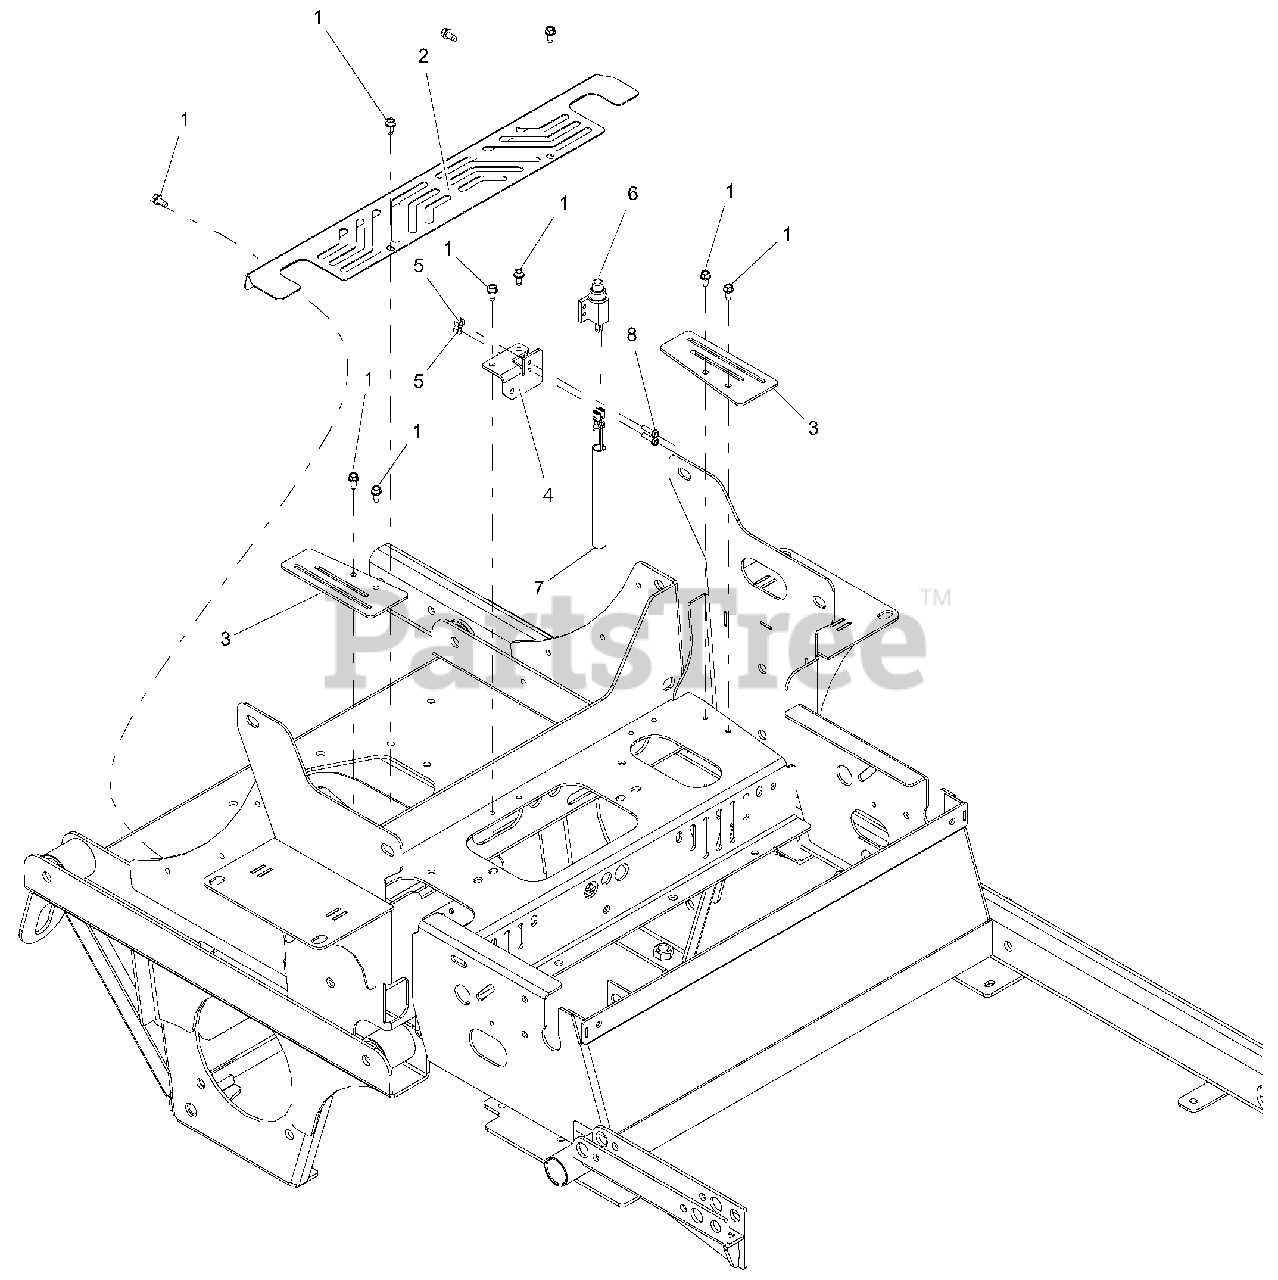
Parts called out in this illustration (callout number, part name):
1	SCR-TAP .25-20X.50 HWH TR YWZ
2	GUARD, CE REAR ACCESS
3	GUARD, SEAT PLATE FINGER
4	BRKT, SEAT SWITCH MOUNT 272-CE (RED)
5	NUT-LK-NYL #10-24 YWZC
6	SWITCH (N.0.) RUBBER SEALED
7	HARNESS, SEAT PLATE SWITCH
8	@SCR-MCH 10-24X.75 HWH YWZC
